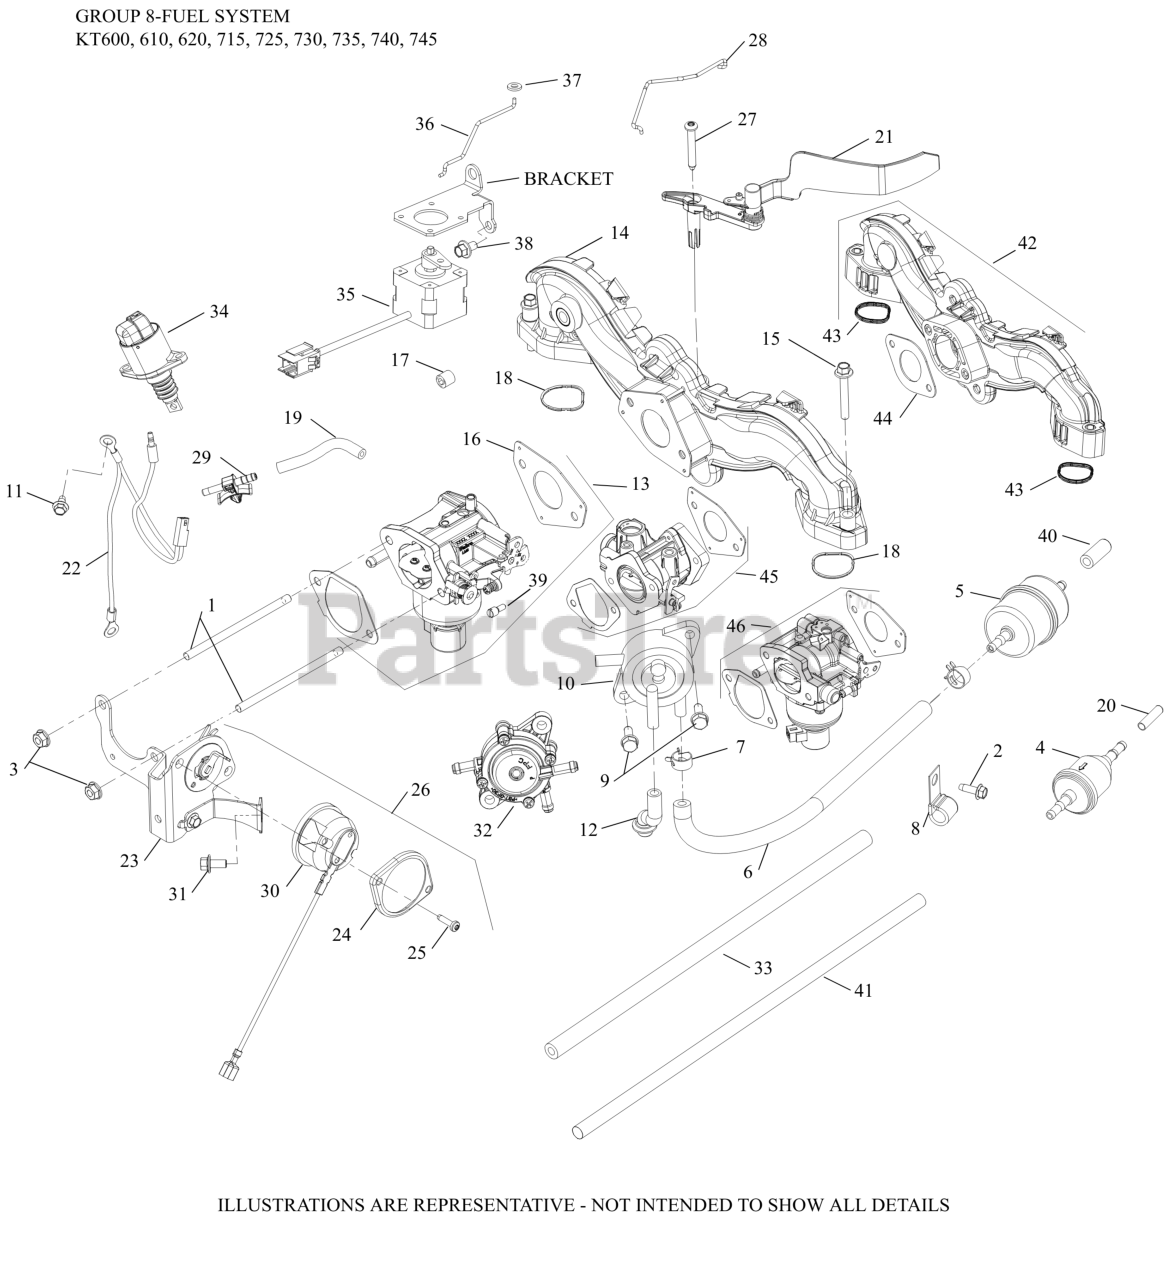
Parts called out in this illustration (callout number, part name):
3	NUT, FLG M6X1.0
4	FILTER,FUEL 51 MICRON (FUEL PUMP)
6	HOSE,LW PERM.FUEL 24.00"-USE 25 111 81-S
7	SPRING CLAMP, HOSE
9	SCREW, TAP M6X1.7X18
10	PUMP, FUEL (PULSE)-(#2539326S)
11	SCREW, THREAD FORMING
12	HOSE, PULSE PUMP(STEEL COVERS)
13	KIT, CARB (WALBRO)
13	KIT, CARBURETOR-(#3285367S)
13	KIT,CARB(WALBRO)
14	KIT, INTAKE MANIFOLD-(#24164277S)
15	SCREW, FLG M6X1.0X40
16	GASKET, CARBURETOR
17	PLUG, CTSK PIPE 1/8"
18	O-RING, INTAKE PORT (PIM)
NI	KIT, HIGH ALTITUDE
NI	SCREW, THROTTLE STOP
NI	KIT,REPAIR OVERHAUL(WALBRO)
NI	KIT,BOWL O-RING(WALBRO)
NI	KIT,SOLENOID REPAIR(WALBRO)
NI	KIT,REPAIR FLOAT(WALBRO)
NI	CLIP, CABLE (KM)
